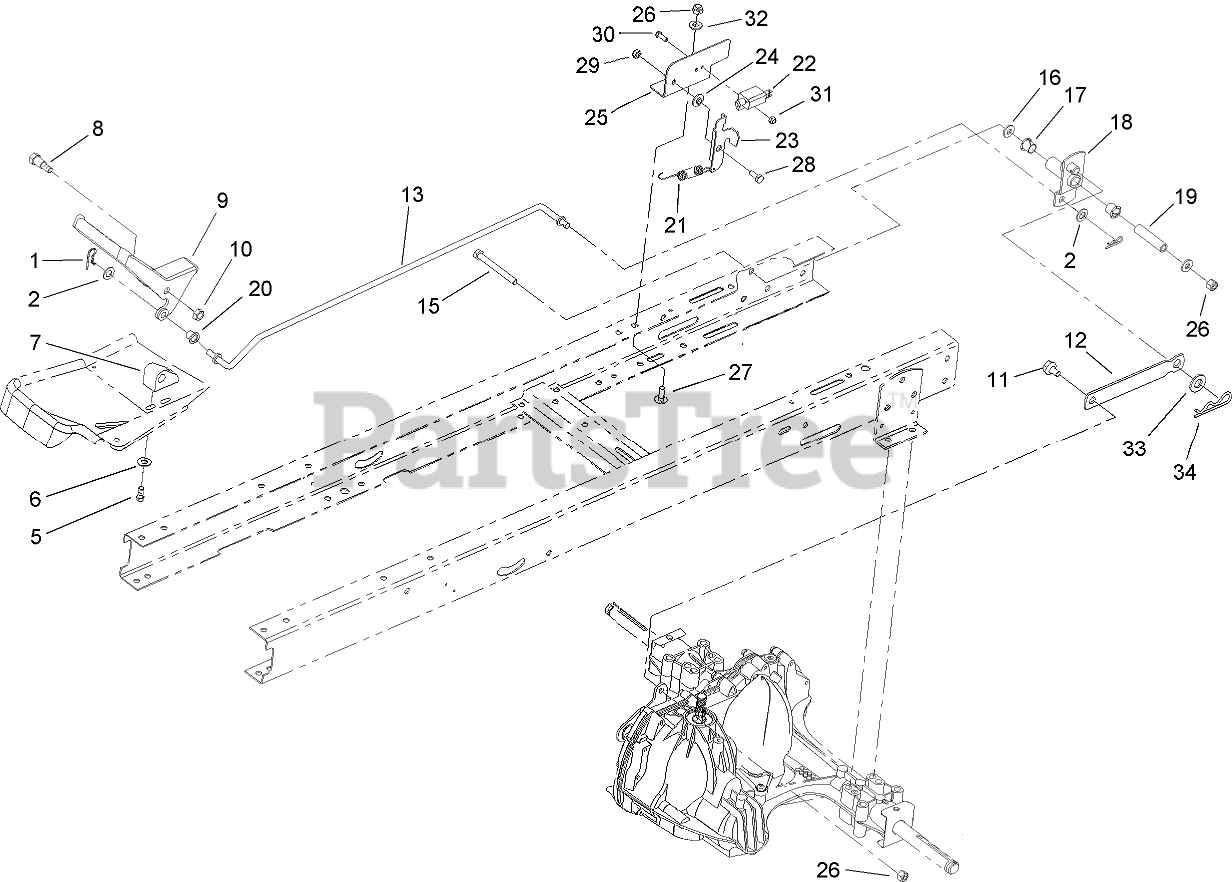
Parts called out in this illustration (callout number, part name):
1	PIN-COTTER
2	WASHER-FLAT
5	SCREW-PLASTITE
6	WASHER-FLAT
7	BLOCK-PIVOT
8	SCREW-SHOULDER, HH
9	PEDAL-CONTROL, SPEED
10	NUT-LOCK, NI
11	BOLT-SHOULDER
12	LINK-CONTROL, SPEED
13	ROD-CONTROL, SPEED
15	SCREW-HH
16	WASHER-FLAT
17	BUSHING-NYLINER
18	PIVOT ASM
19	SPACER-PIVOT
20	BUSHING-FLANGED
21	SPRING-EXTENSION
22	SWITCH-POLE, SINGLE
23	BRACKET-PIVOT
24	WASHER-STEPPED
25	BRACKET-ADJUSTMENT
26	NUT-LOCK, NI
27	SCREW-CARR
28	SCREW-HHF
29	NUT-LOCK, NI
30	SCREW-SHH
31	NUT-LOCK
32	WASHER-PLAIN
33	WASHER-FLAT
34	PIN-HAIR
